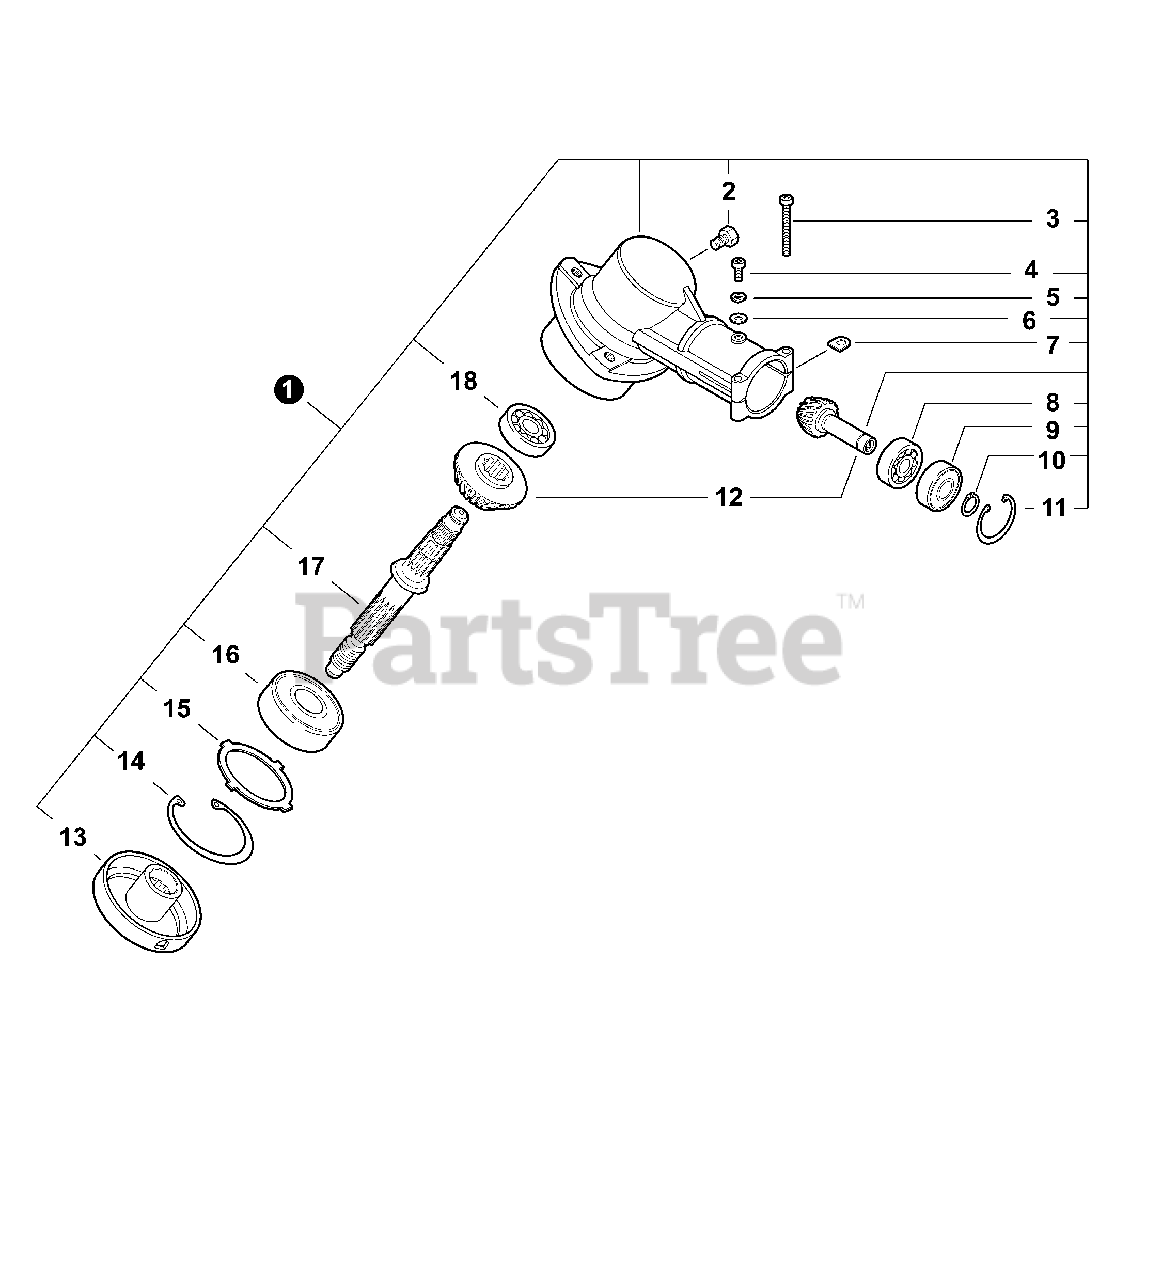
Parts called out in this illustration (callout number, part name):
1	GEAR CASE ASSY
2	BOLT M8×8
3	BOLT, TORX 5×25
4	BOLT, TORX 5×10
5	WASHER, SPRING 5
6	WASHER, FLAT 5.5×10×0.8
8	BEARING, BALL 6900
9	BEARING, BALL 6900Z
10	RING, SNAP Ø10
11	RING, SNAP Ø22
12	GEAR SET
13	PLATE, ADAPTOR - UPPER
14	RING, SNAP Ø32
16	BEARING, BALL 6201
17	SHAFT, GEAR
18	BEARING, BALL 609
